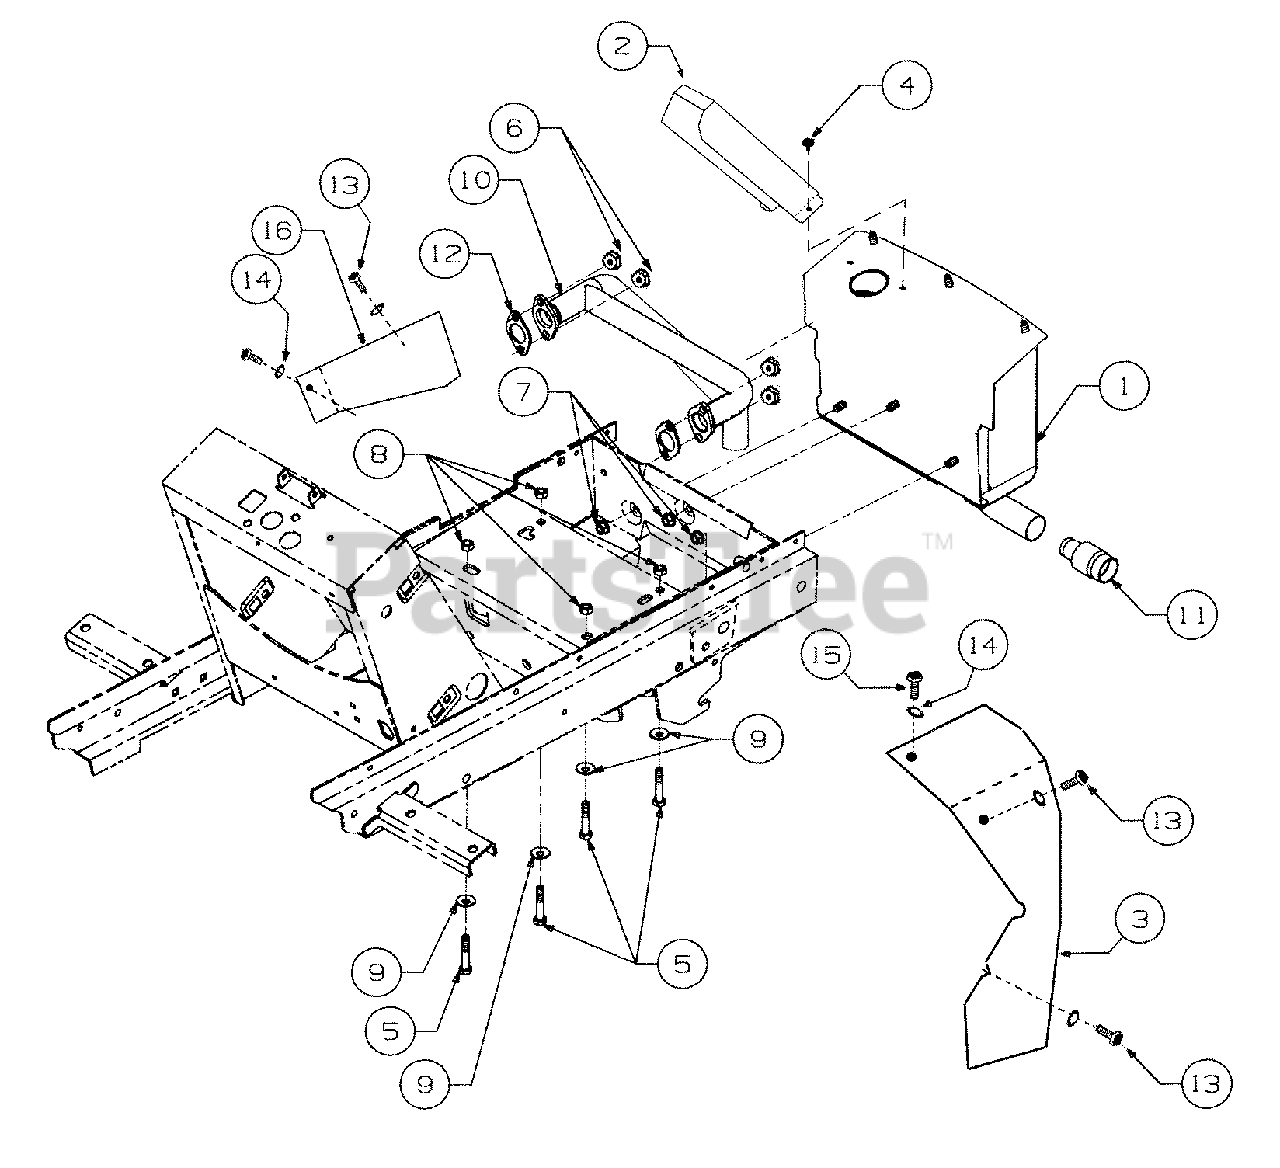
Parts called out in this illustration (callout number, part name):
1	Muffler Assembly
2	Shield, Muffler Tube
3	Baffle, RH Heat
4	Screw, Hex Wsh Hd Tap, #10-16 x .38
5	Bolt, Eng Mount, 3/8-24 x 1.75 GR5
6	Nut, Hex Flange
7	Nut, Hex Flange Lock, 5/16-18
8	Nut, Hex Lock, 3/8-24
9	Washer, Bell, .380 x .88 x .062
10	Tube, Exhaust
11	Arrestor, Spark
12	Gasket, Exhaust
13	Screw, Hex Cap, M6 x 1 x 10
14	Washer, Flat, .281 x .5 x .06
15	Screw, Truss Hd Tapp, #10 x .5
16	Baffle, LH Heat
